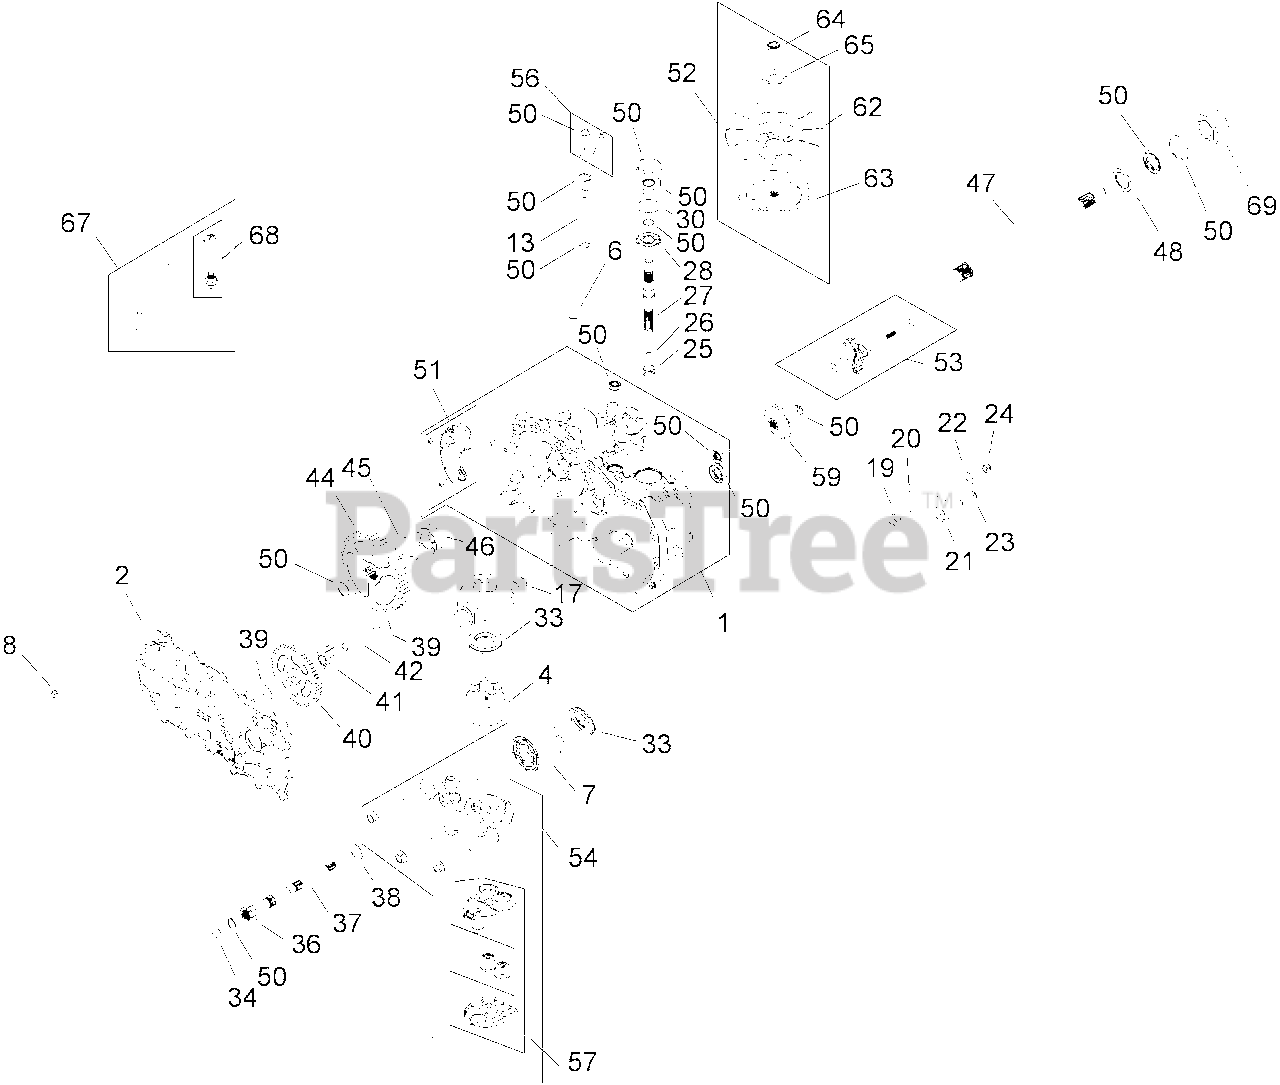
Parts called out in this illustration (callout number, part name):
1	LH MAIN HOUSING ASM
2	LH SIDE ASM
4	PUMP BLOCK ASM
6	PLUG
7	CYLINDER BLOCK KIT
8	SCREW-HHF
13	ROD-BYPASS
17	SWASHPLATE-TRUNNION
20	PUCK-FRICTION
21	ARM-CONTROL
22	WASHER-PIVOT
25	SPRING-BLOCK
26	WASHER-THRUST, BLOCK
27	SHAFT-INPUT
28	BEARING-BALL
33	BEARING-THRUST
34	WASHER-FLAT
36	GEAR-PINNION, 13T
37	SHAFT-MOTOR
38	WASHER-SHAFT, MOTOR
41	GEAR-JACKSHAFT, 10T
42	PIN-JACKSHAFT
44	GEAR-52T, BULL
46	BEARING-SLEEVE
47	SHAFT-AXLE
48	BUSHING-AXLE
51	LH EXPANSION PLATE KIT
52	Fan Pulley Kit
53	BRAKE ARM KIT
54	LH CENTER SECTION FILTER KIT
56	BYPASS ARM KIT
57	FILTER KIT
59	DISC-BRAKE, COG
62	FAN-6 INCH, 10 BLADE
65	WASHER-SLOTTED
67	BREATHER KIT
68	BREATHER ASM
69	COVER-NUT, AXLE
